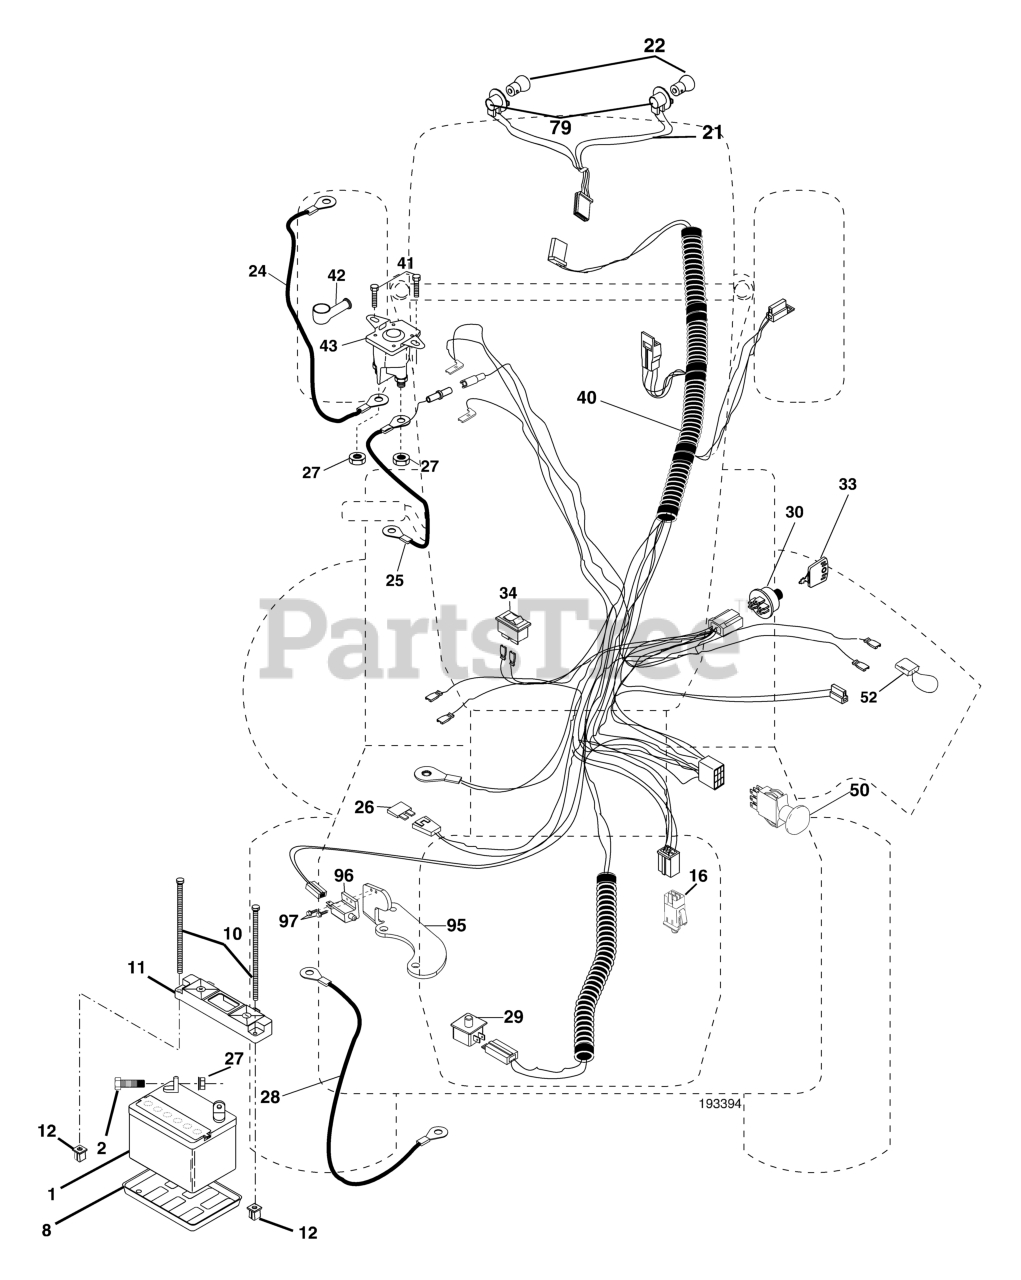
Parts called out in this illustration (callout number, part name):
1	BATTERY 12V .35 AMP
2	BOLT.HEX.1/4.X.3/4.DICHROMATE
8	BATTERY TRAY T
10	BOLT 1/4-20 X 7.5
11	BATTERY HOLDDOWN FRONT MOUNT
12	NUT, PUSH NYLON 1/4" BATTERY
16	SWITCH INTERLOOK PUSH-IN
21	HARNESS.W/LIGHT SOCKET
24	CABLE.STARTER.6GA.22"RED
25	CABLE, BATTERY
27	NUT
28	CABLE, GROUND
29	SWITCH.SEAT.DP W/RAMPS
30	SWITCH.IGN.DELTA.W.LGH.ROS
33	KEY MLD GEN DELTA
40	HARNESS.IGN.REG.RECT
41	SCREW
42	TERMINAL COVER
43	SOLENOID
50	RP.PTO.SWITCH.8 TERMINAL.BLACK
52	WIRE PROTECTION LOOP
79	BULB HOLDER ASM.
95	BRKT.ROS.6SP
96	SWITCH-INTER. GT
97	SCREW.HEX.WSH.SLT.#10-24X.50
